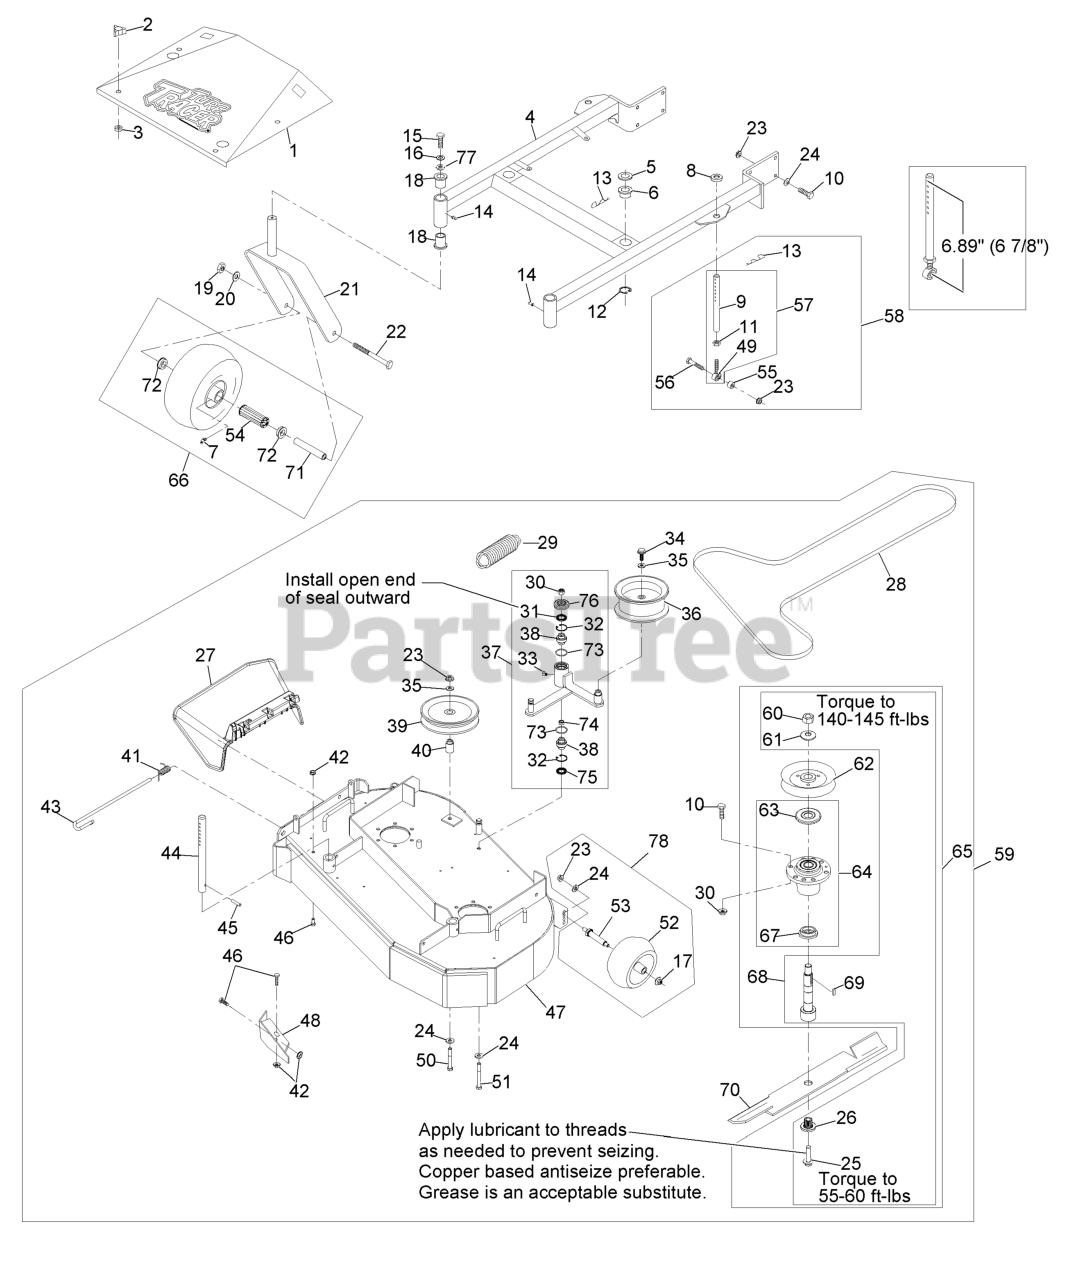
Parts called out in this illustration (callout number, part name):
1	ASM,SHIELD W/DECALS 36 TT
2	KNOB-3 PRONG
4	DECK SUPPORT W/BSHGS 36"
5	SPACER-DECK SUPPORT
6	BUSHING-DECK
7	FITTING-GREASE
9	LINK,SUPPORT
10	SCREW-HH
11	NUT-HJ
12	RING-RETAINING
13	PIN,HAIR COTTER
14	FITTING-GREASE
15	SCREW-HH
16	WASHER-LOCK
17	Nut-Nyloc 3/8-16 Flg
18	BEARING-FLANGED
19	NUT-HH
20	WASHER-LOCK
22	SCREW-HH
23	NUT-HHF, WHIZ
24	WASHER-BELLEVILLE
25	SCREW,SEMS 1/2-20 X 2.19
26	BUSHING,SPLINED
27	CHUTE DEFLECTOR XRK M056
28	BELT,DECK DRIVE
30	NUT-LOCK, NI
31	SEAL-LIP, SINGLE
32	RING-SNAP
33	FITTING-GREASE, 90 DEG
34	SCREW-HHF
35	WASHER-FLAT
36	IDLER-PULLEY, FLAT
37	KIT, DECK IDLER TTHP 36"(
38	BEARING-SPHERICAL
39	PULLEY-IDLER
40	BUSHING-IDLER
41	SPRING, TORSION
43	PIN-CHUTE
44	ROD,DECK SUPPORT
46	SCREW-HH
47	ASM,DECK W/DECALS TTHP/MH
48	BAFFLE,DOGLEG
49	BALLJOINT
50	SCREW-HH
51	SCREW-HH
52	ROLLER-SCALP, ANTI
54	BEARING
56	SCREW-HH
58	KIT,SUPPORT LINK W/PIN
59	Assembly, Cutting Deck Complete
62	SHEAVE,W/HUB 5.72
63	GUARD-BEARING, TOP
64	KIT, CUTTER HOUSING
65	ASM, CUTTER HSG
66	KIT, SP CASTER WHEEL REPL
67	SPACER-GUARD, BOTTOM
68	KIT, SPLINED SPINDLE 103-
69	KEY-RECTANGLE
72	BUSHING
75	SEAL-LIP, DOUBLE
76	GUARD-TOP
